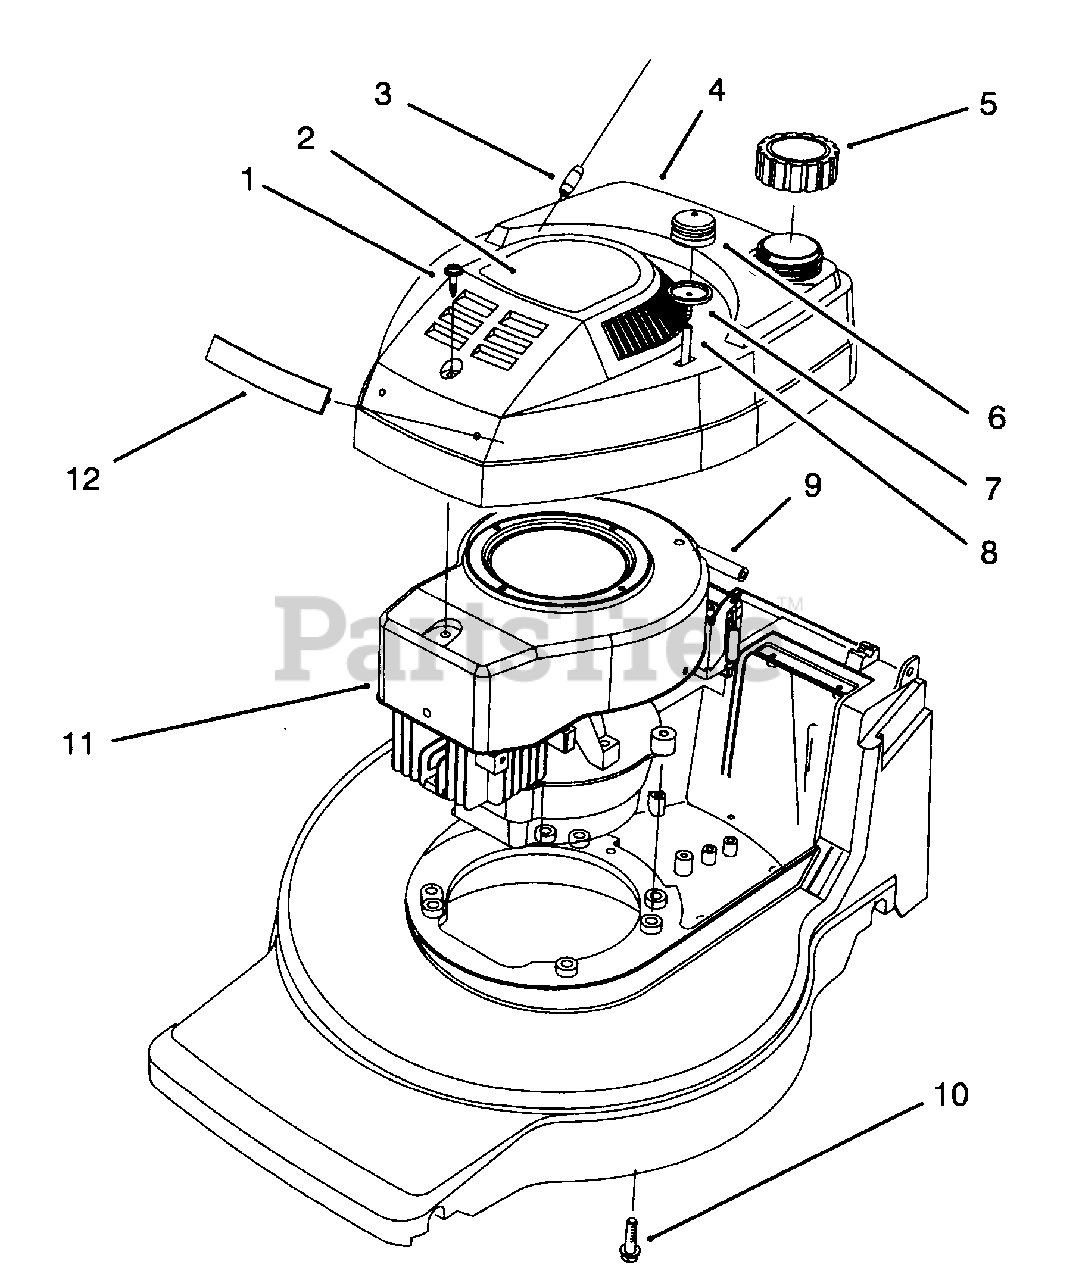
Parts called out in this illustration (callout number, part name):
1	Screw-Sems
2	Decal-Shroud
3	Rope-Stop
4	Tank Shroud Assembly
5	Cap-Gas
6	Bulb-Primer
7	Body-Primer
8	Hose-Primer
9	Line-Gas
10	Screw-Engine
12	Decal-Shroud
